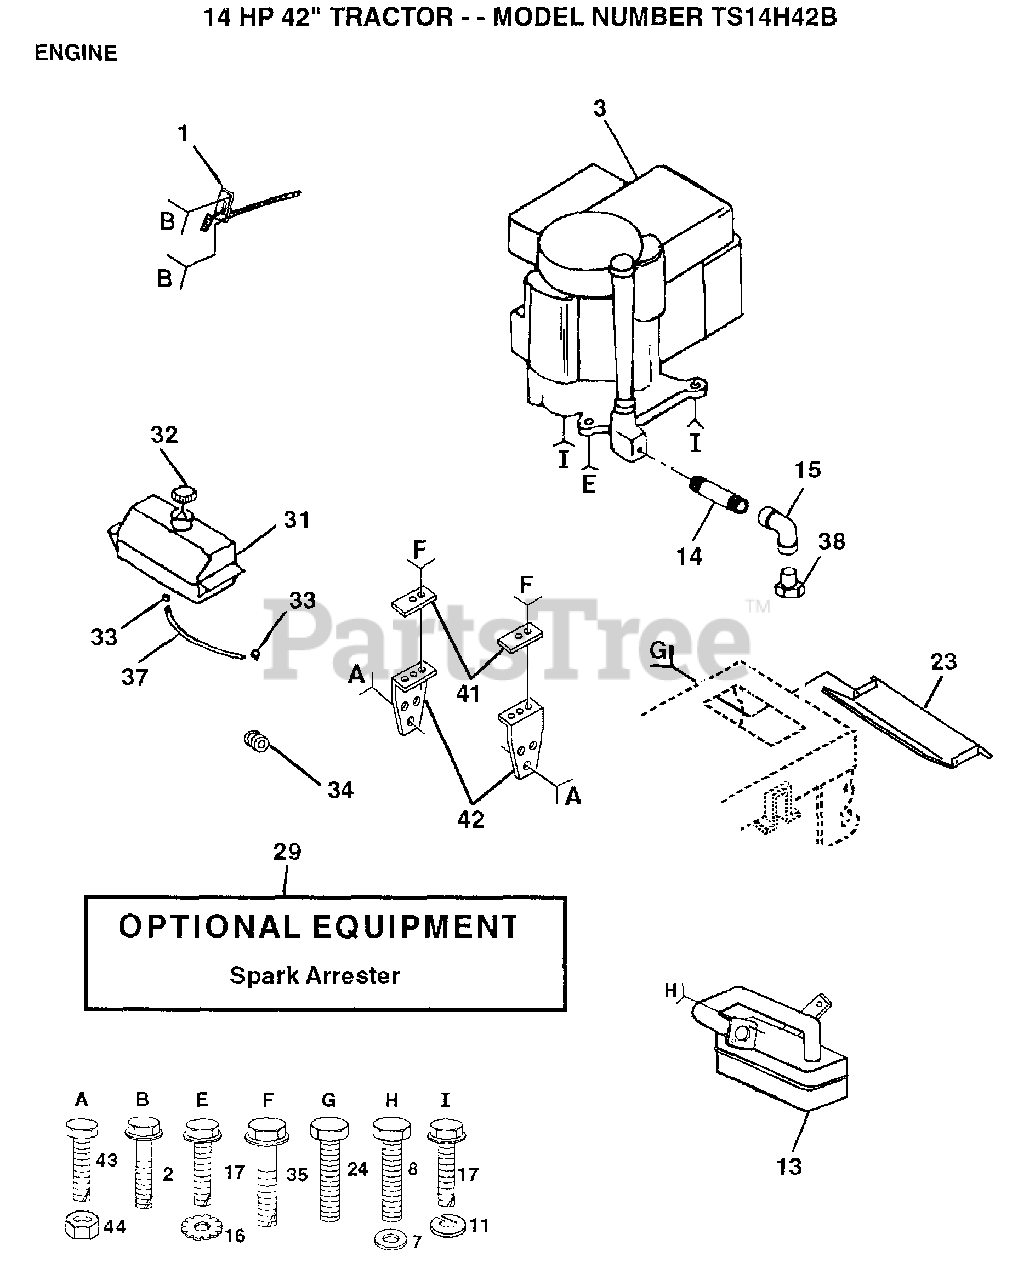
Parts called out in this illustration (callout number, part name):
1	THROTTLE CONTROL
2	SCREW LT
8	BOLT
11	LOCKWASHER
13	MUFFLER.LT.12.5
14	PIPE NIPPLE
15	ELBOW
16	LOCKWASHER.5/16.E
24	SCREW
31	TANK.FUEL.LT.
32	CAP ASM FUEL
33	HOSE CLAMP
35	SCREW
37	LINE FUEL
41	"CLAMP,FUEL TANK T"
42	BRKT FUEL TANK T
43	BOLT
44	NUT
